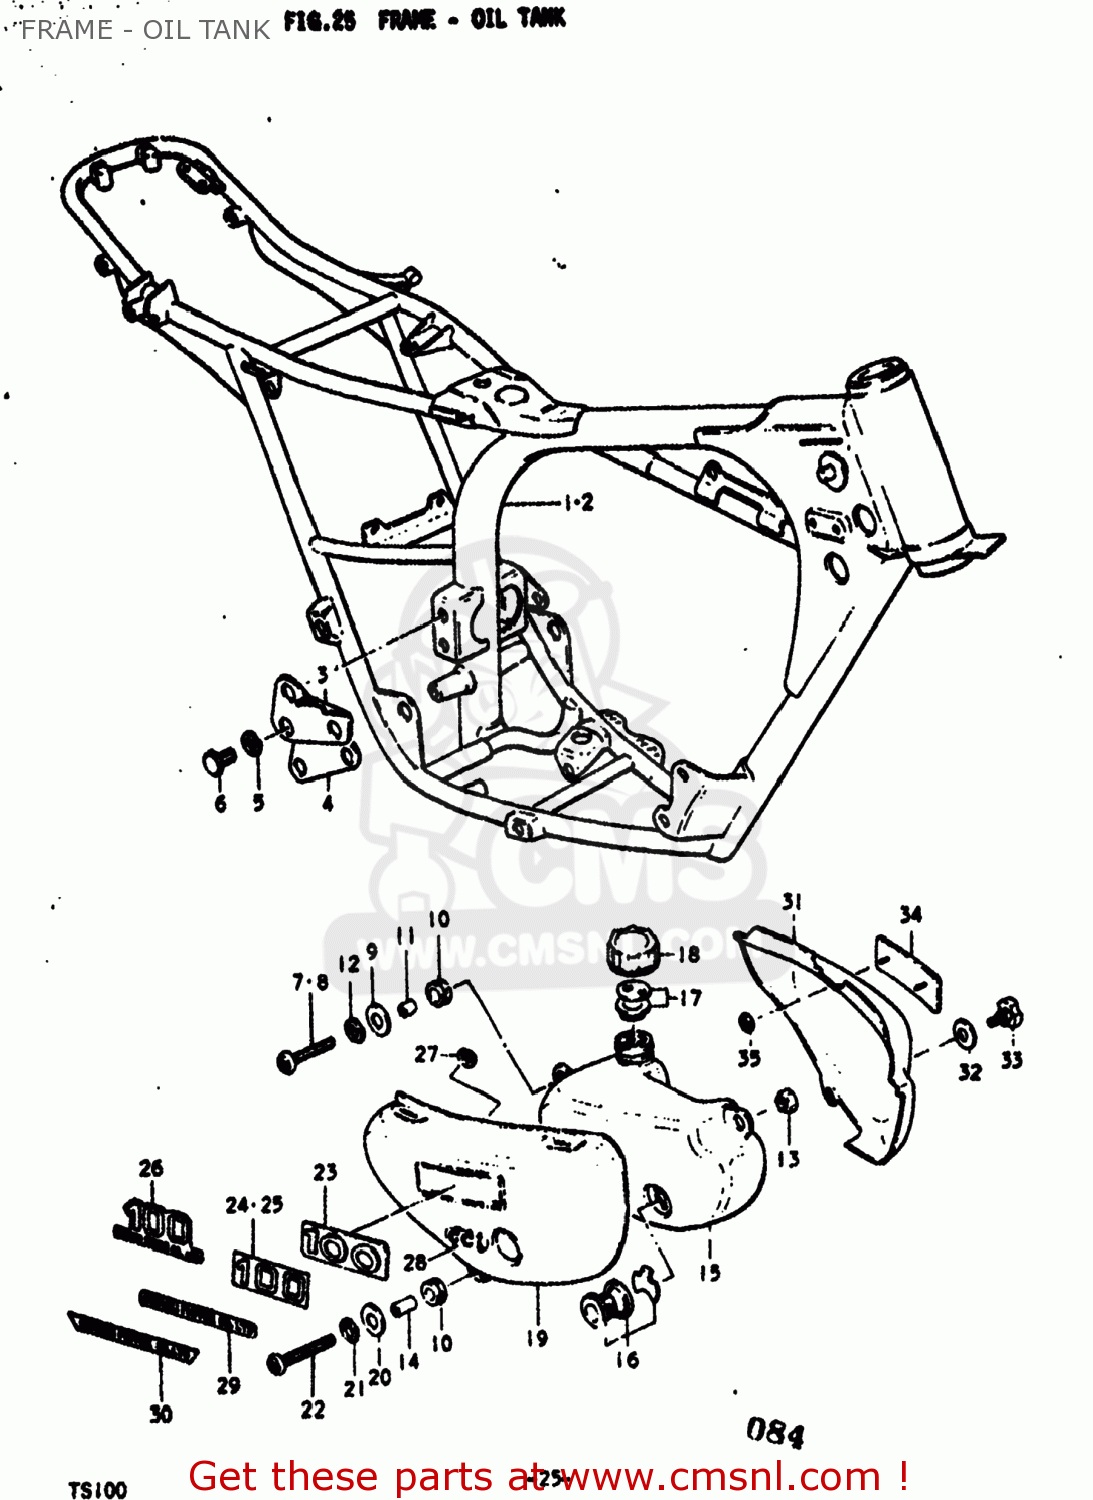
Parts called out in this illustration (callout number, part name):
1	FRAME
2	FRAME
3	PLATE,ENGINE MOUNTING
4	PLATE,ENGINE MOUNTING
5	LOCK WASHER
6	BOLT
7	SCREW
8	SCREW
9	WASHER
10	CUSHION
11	SPACER (6.8X10X10)
12	LOCK WASHER
13	NUT
14	SPACER
15	TANK,OIL
16	LENS SET,OIL LEVEL
17	LENS,OIL LEVEL INSPECTION
18	CAP,OIL TANK
19	COVER,FRAME,RIGHT
20	WASHER
21	LOCK WASHER
22	SCREW
23	EMBLEM,FRAME COVER
24	EMBLEM
25	EMBLEM
26	EMBLEM
27	NUT
28	EMBLEM
29	LABEL,COMPANY NAME
30	LABEL (COMPANY NAME)
31	COVER,FRAME,LEFT
32	NUT (5MM)
33	KNOB,FRAME COVER
34	EMBLEM,FRAME COVER
35	NUT
